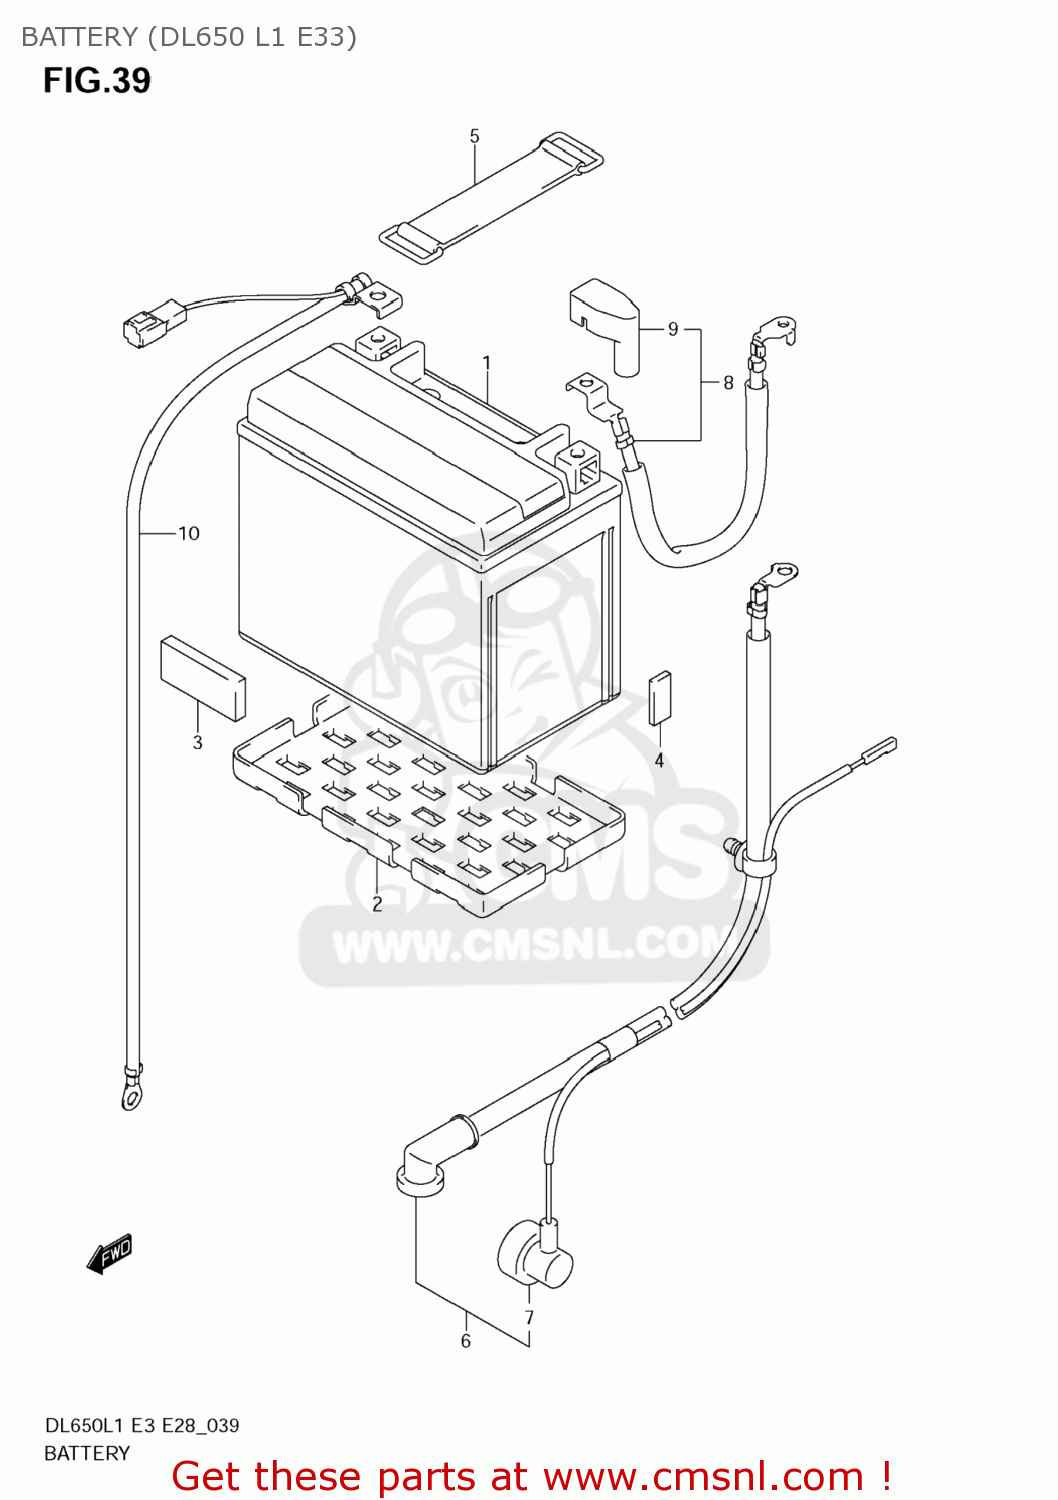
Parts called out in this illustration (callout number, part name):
1	BATTERY ASSY(YTX12-BS,12V10AH)
2	PROTECTOR,BATTERY
3	PROTECTOR,BATTERY(70X100X6)
4	CUSHION,FUEL TANK NO.2
5	BAND
6	WIRE,STARTER MOTOR LEAD
7	CAP,OIL PRESSURE SWITCH
8	WIRE,BATTERY PLUS LEAD
9	CAP,BATTERY PLUS LEAD
10	WIRE,BATTERY MINUS LEAD
